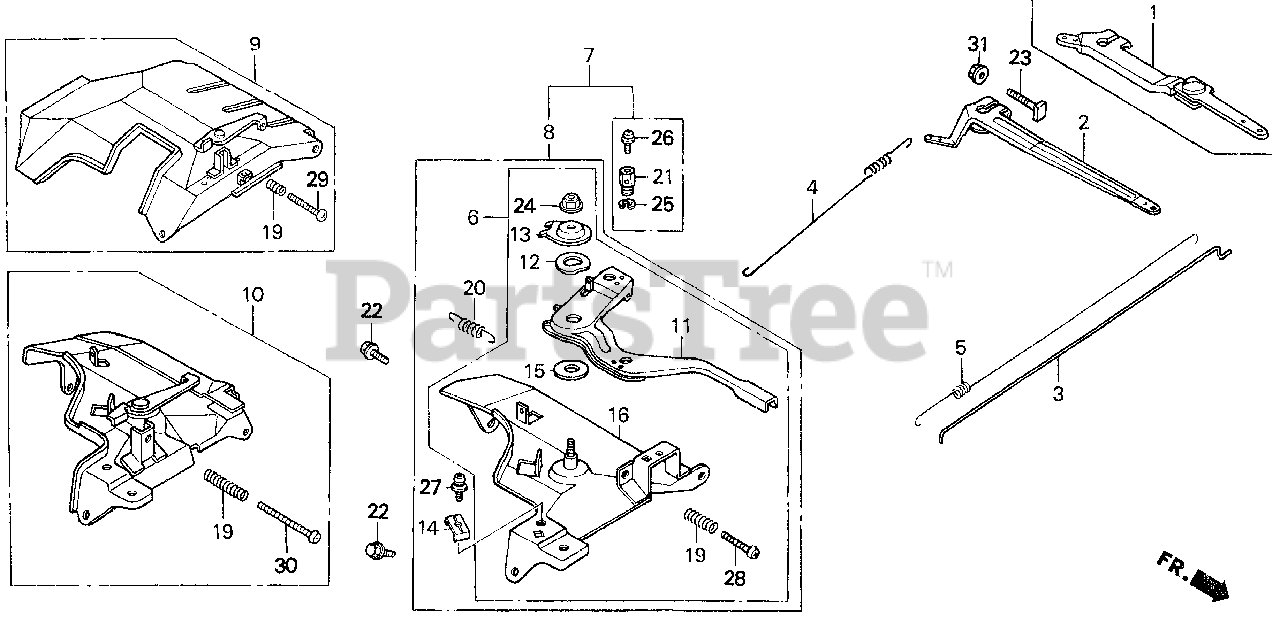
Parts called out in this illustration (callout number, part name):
1	ARM, GOVERNOR
3	ROD, GOVERNOR
4	SPRING, GOVERNOR
5	SPRING, THROTTLE RETURN
9	CONTROL ASSY.
19	SPRING, CONTROL ADJUSTING
22	BOLT, FLANGE (6X12) (CT200)
23	BOLT, GOVERNOR ARM
29	SCREW, PAN (5X35)
31	NUT, FLANGE (6MM)
